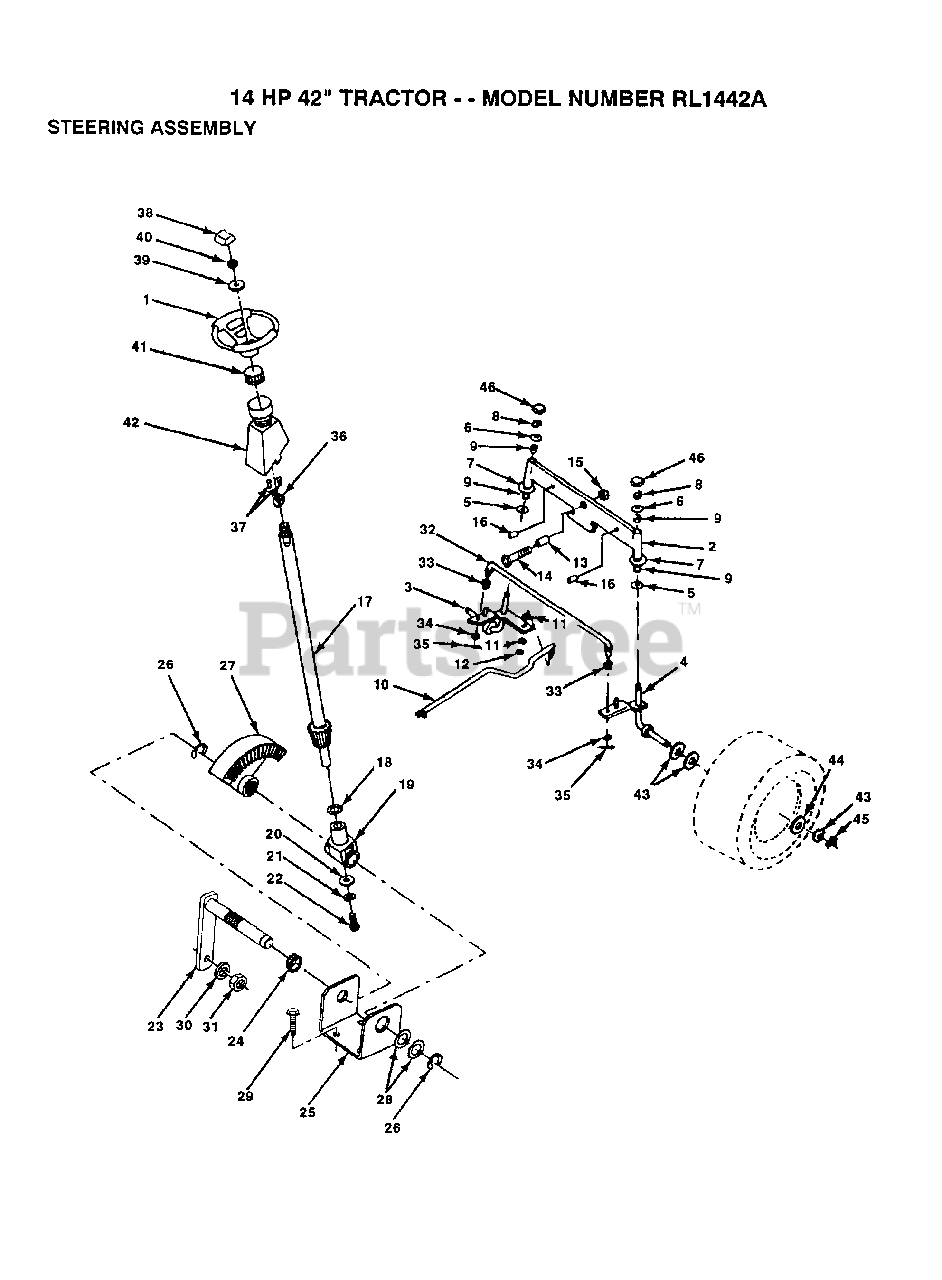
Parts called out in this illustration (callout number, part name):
3	SPINDLE LH
4	SPINDLE RH
5	WASHER .T
6	WASHER
7	WASHER
8	RING
9	COL. SRTG. BEAR.
11	LOCKWASHER
13	BEARING
14	BOLT HEX 5/8-11
16	AXLE PIN
17	SHAFT ASM
18	THRUST WASHER
19	SUPPORT.SHAFT
21	LOCKWASHER
22	"SCREW,SPECIAL"
24	NYLINER T
25	"BRKT,STEERING"
26	RING
28	WASHER .T
29	SCREW
30	LOCKWASHER
32	TIE ROD
33	BUSHING.DRAGLINK
34	WASHER
35	COTTER PIN
38	ST WHL INSERT CAP
39	WASHER T
40	GRIPCO NUT
41	ADAPTER-WHEEL LT
42	"TUBE, STR SHAFT"
43	WASHER
44	WASHER
45	RING
46	CAP
